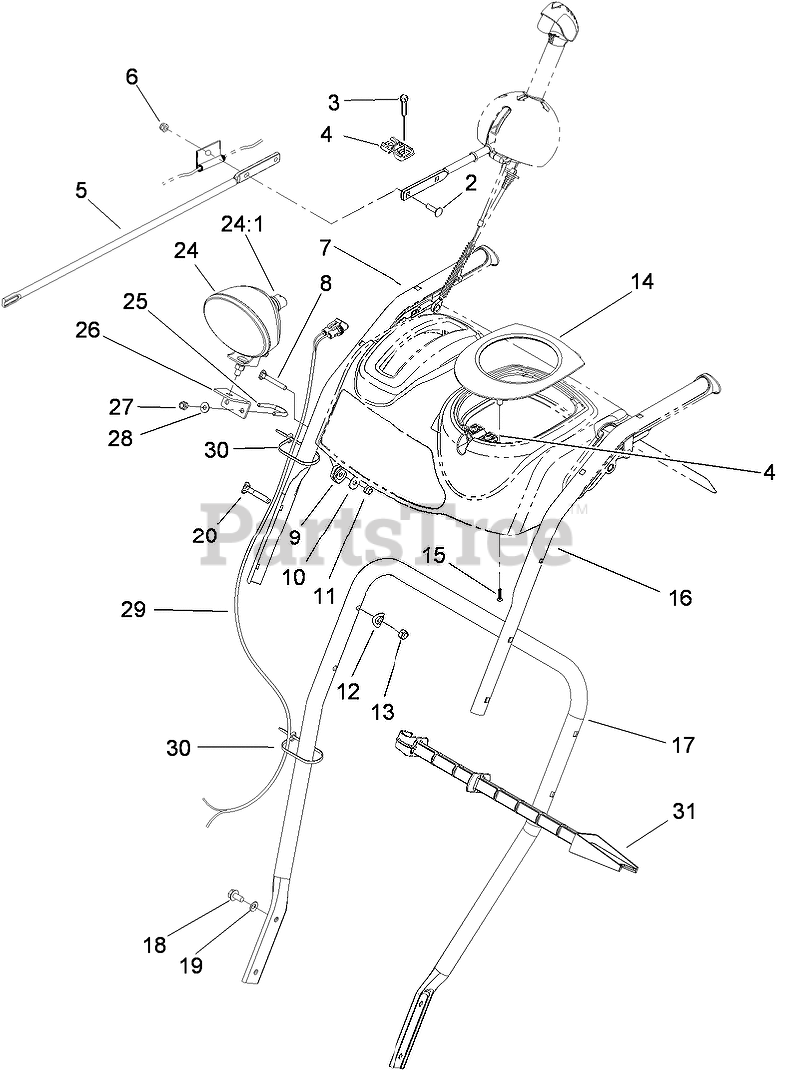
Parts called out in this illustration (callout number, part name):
2	SCREW-CARR
3	SCREW-PLASTITE
4	SUPPORT-ROD
5	ROD-CHUTE, FRONT
6	NUT-LOCK, NI
7	HANDLE-UPPER, RH
8	SCREW
9	CLAMP-CABLE
10	WASHER-PLAIN
11	NUT-LOCK, NI
12	WASHER
13	NUT-LOCK, NI
14	COVER-PANEL, CONTROL
15	SCREW-PPH
16	HANDLE-UPPER, LH
17	HANDLE-LOWER
18	SCREW-HWHTF
19	WASHER-BELLEVILLE
20	SCREW-HANDLE
24	HEADLAMP ASM
24:1	LAMP-12 VOLT
25	CLAMP
26	BRACKET-LIGHT
27	NUT-LOCK, NI
28	WASHER-FLAT
29	HARNESS-WIRE
30	TIE-CABLE
31	STICK-CLEANOUT
